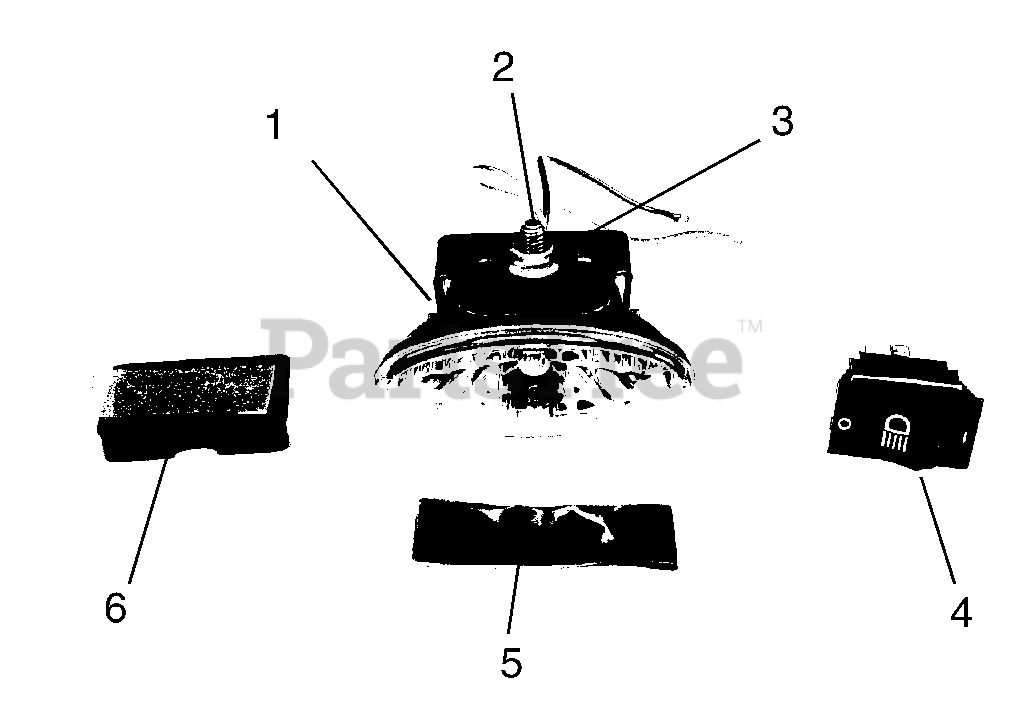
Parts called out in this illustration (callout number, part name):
1	LIGHT-CONS RIDE ON- SEE B-2124
2	BLT-RDHDSQNK .31-18X.75 G5BZ
3	@NUT-SPNLK-FLG .312-18 YWZC
4	SWITCH - LIGHT
5	VHB TAPE 4941F
6	BLOCK,SHIFT LEVER
